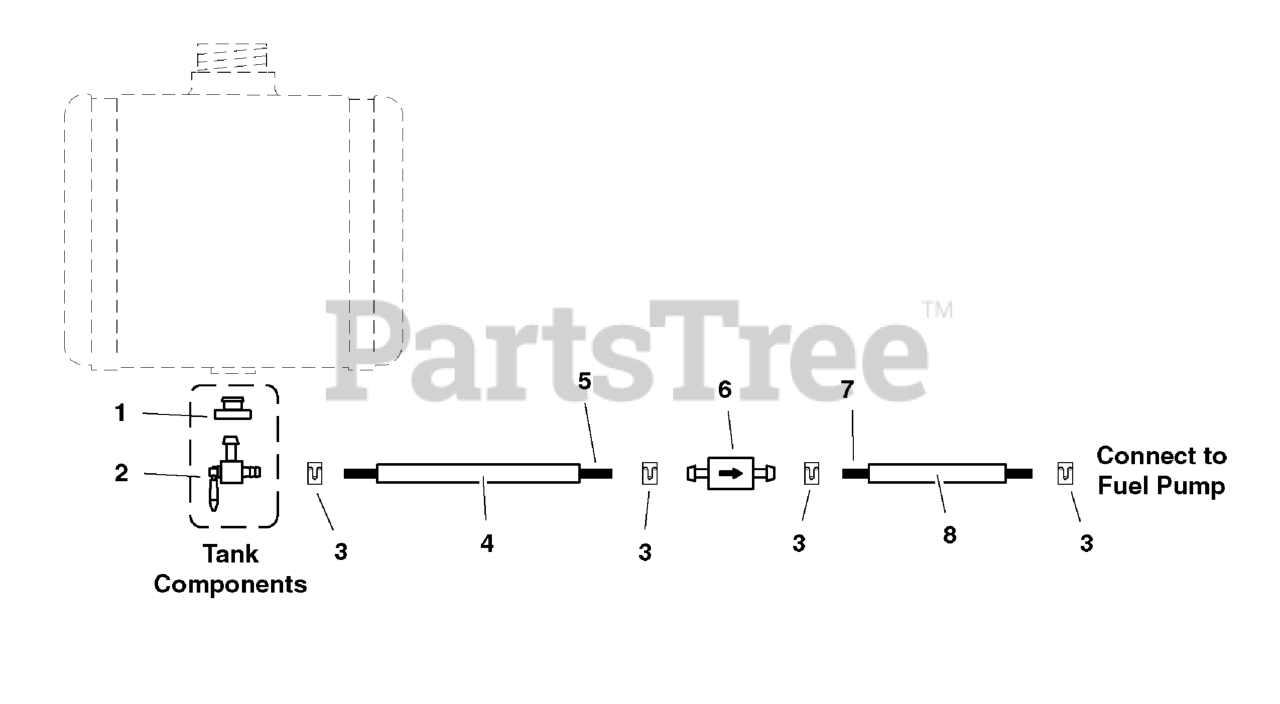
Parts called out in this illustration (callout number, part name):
1	BUSHING-FUEL TANK RED RUBBER
2	FUEL SHUTOFF VALVE
3	CLAMP, Hose
4	WIRE LOOM, 24"
5	1/4" Fuel Line, 25" Long
6	FUEL FILTER
7	1/4" Fuel Line, 19" Long
8	WIRE LOOM, 16"
